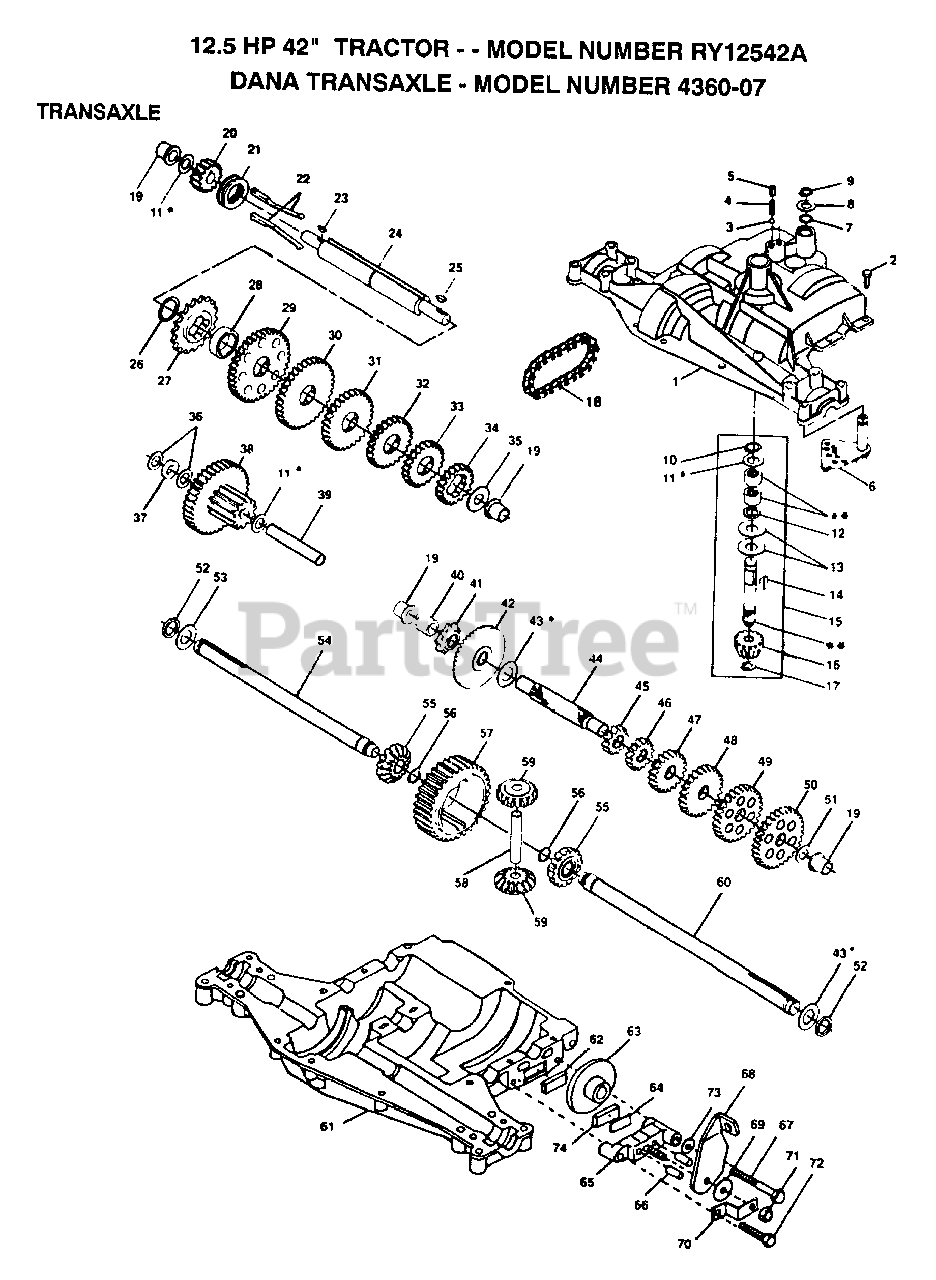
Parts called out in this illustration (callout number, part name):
2	WASHER
3	SCREW
4	SPRING COMPRESSIO
5	BTRY FENDER PLATE
6	HOSE CLAMP T
7	PAD FOOTREST
8	SCREW
11	NUT
14	NUT
16	BOLT
17	DRAWBAR
18	"CLIP,INSULATOR"
